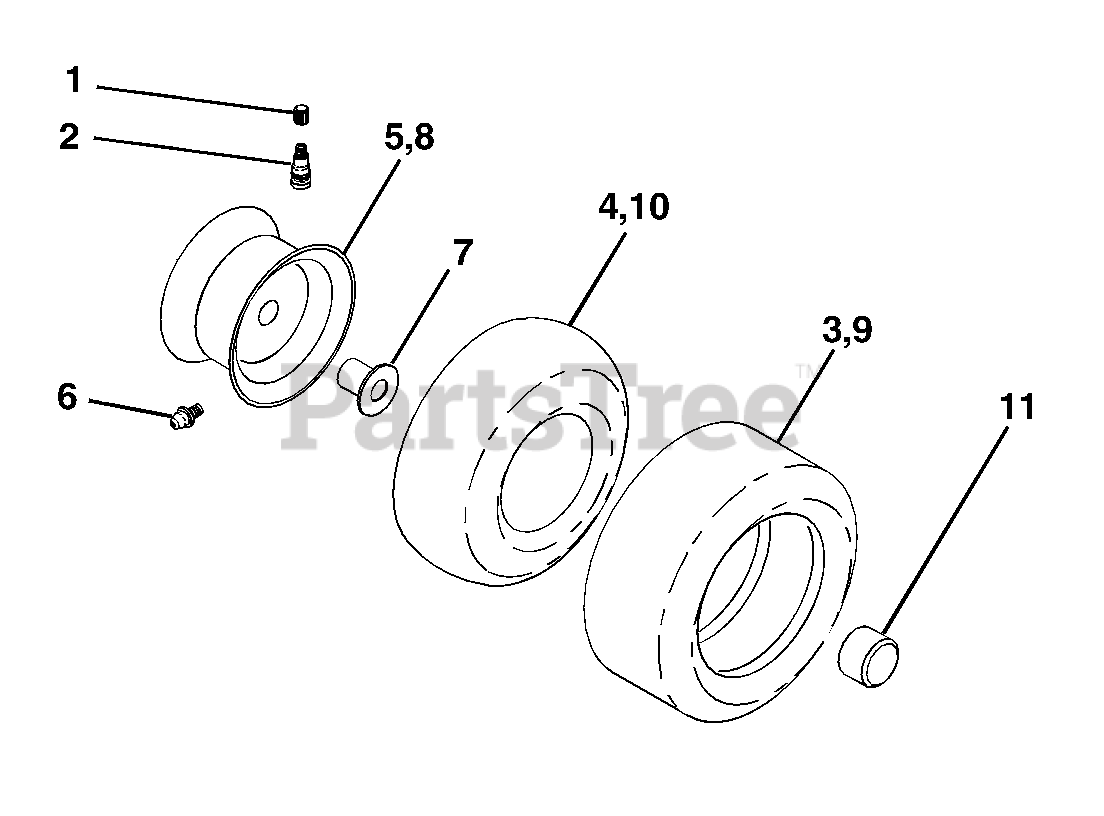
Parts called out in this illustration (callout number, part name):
1	Cap Valve Tire
2	Stem Valve
3	Tire F Ts 15 x 6 0 - 6 Service
4	Tube Front (Service Item Only)
5	Rim Asm 6"front Silver Service
6	Fitting Grease (Front Wheel Only)
7	Bearing Flange (Front Wheel Only)
8	Rim Asm 8"rear Silver Service
9	Tire R Ts 20 x 10-8 C Service
10	Tube Rear (Service Item Only)
11	Cap Axle Blk 1 50 x 1 00
